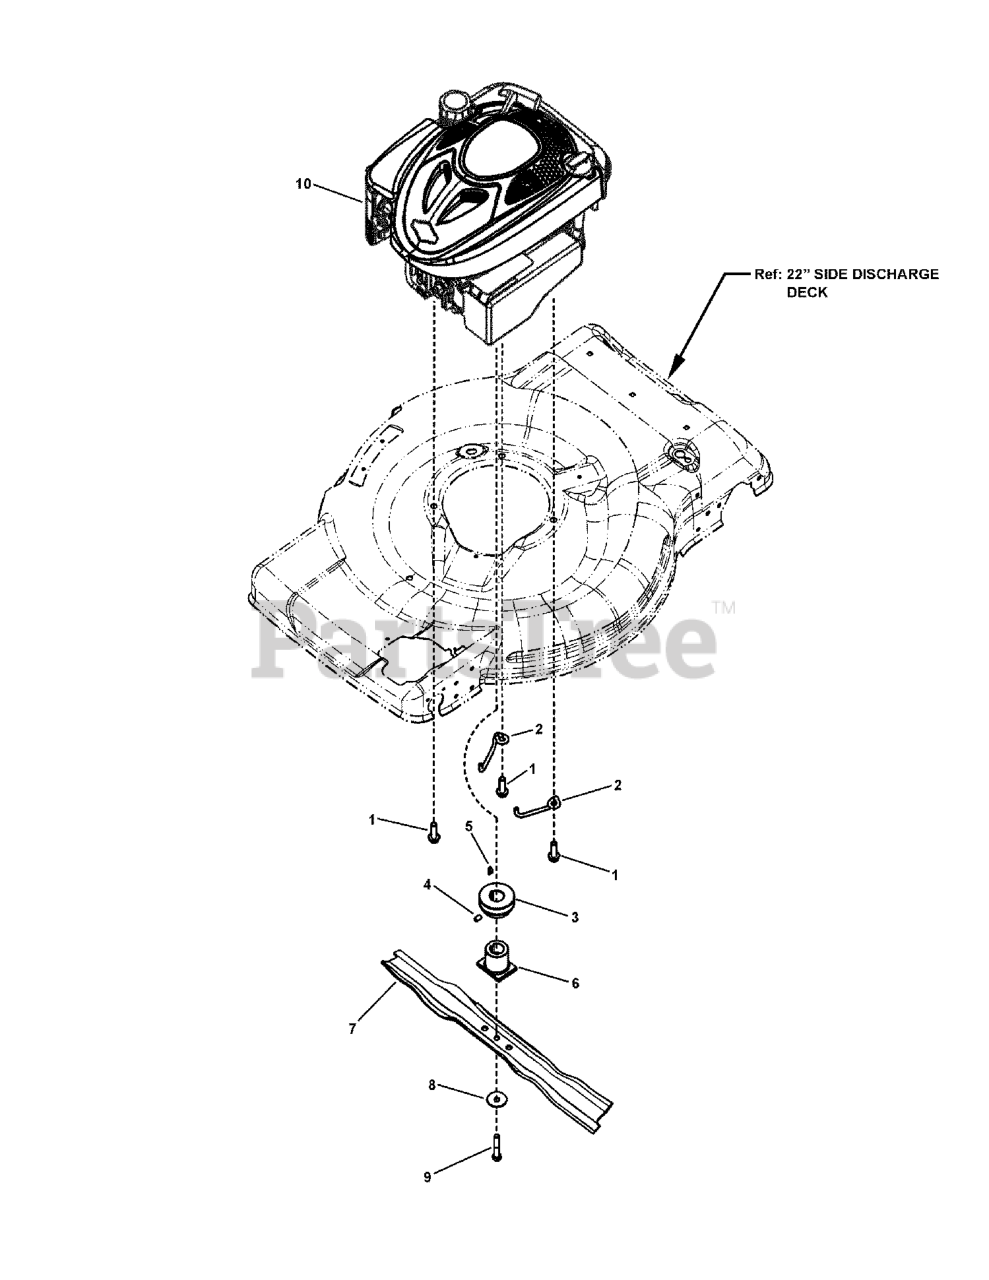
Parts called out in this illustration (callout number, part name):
1	SCREW, 3/8-16 x 1-1/4" Hex Washer Self-Tap
2	BELT GUIDE, Engine, Front Wheel Drive
3	PULLEY, Engine
4	SET SCREW, 5/16-18 x 1/2" Hex Recess
5	KEY, #HP-506 Hi-Pro
6	BLADE HUB, 21" WBM, Rear Discharge, 2 Position
7	BLADE, Wave, Steel Deck
8	WASHER, Cone
9	SCREW, 3/8-24 x 2" Hex Head Cap, GR 5
10	* ENGINE, B&S, 675 Series, X-Spec, B1, FC
